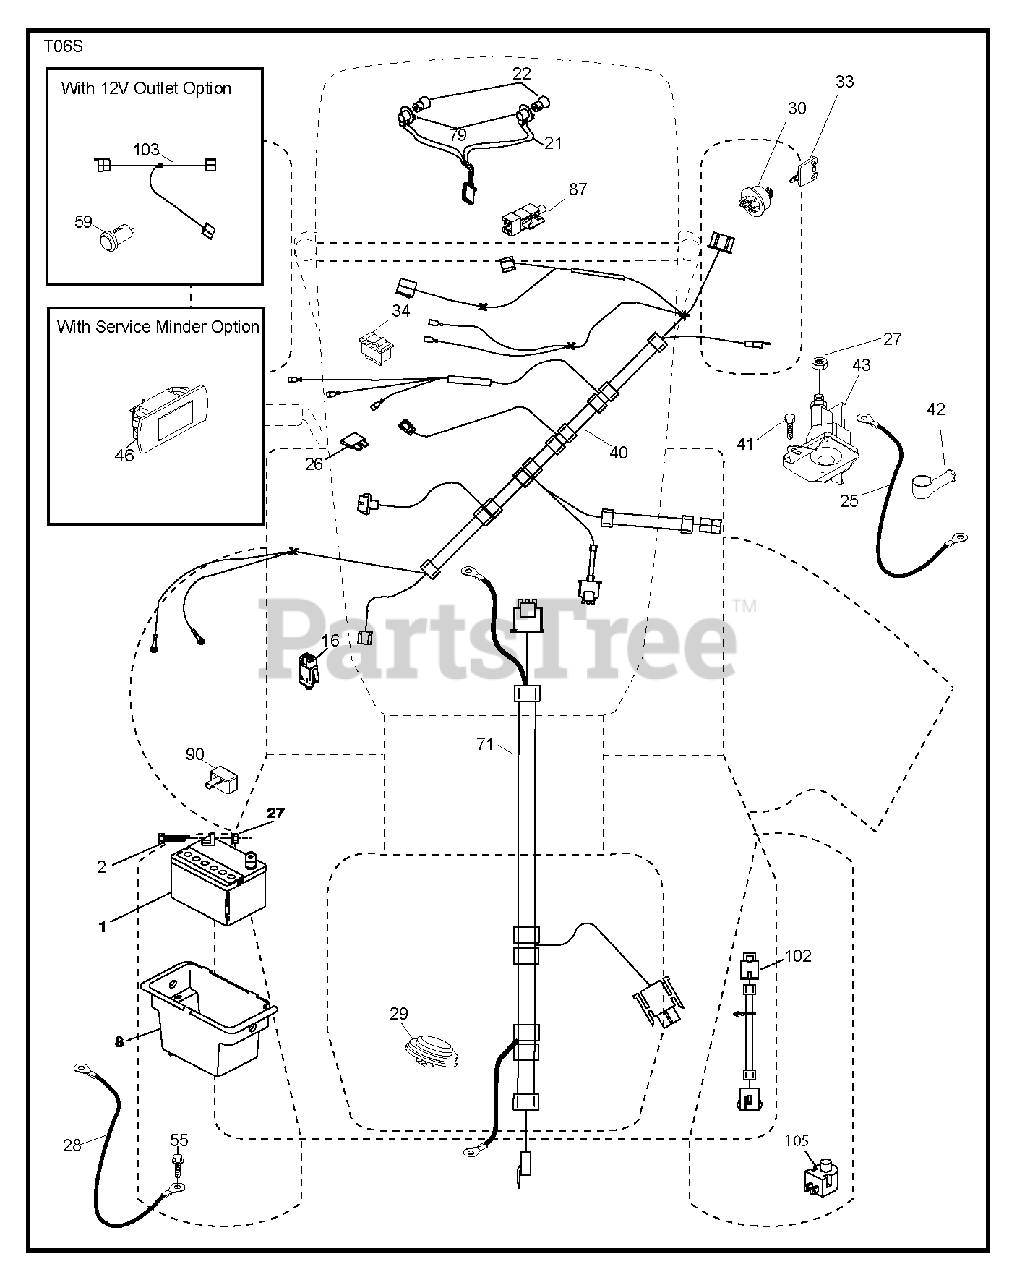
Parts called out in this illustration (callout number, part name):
1	Battery, Dry 30 Amp
2	BOLT.HEX.1/4.X.3/4.DICHROMATE
8	BOX.BATTERY.MNT.REAR.L
16	SWITCH INTERLOOK PUSH-IN
21	HARNESS.LIGHT W/4152J BULBS
25	CABLE.BATT.RED.8GA.17
26	FUSE 20AMP
27	NUT
28	CABLE.GROUND.REAR.BATTERY.8G
29	SWITCH.SEAT.DELTA.OPC.
30	SWITCH.IGN.DELTA.W.LGH.ROS
33	KEY.CHAIN.BLISTER.PACK.GEN.USA
40	HARNESS IGN. DASH
41	SCREW
42	TERMINAL COVER
43	SOLENOID.W/BRASS.PLUNGER
46	RP GUAGE.SRVCMNDR.HRMTR.
55	SCREW 5/16"
71	HARNESS.TEX.CHSSIS.REAR.BATT
79	BULB HOLDER ASM.
87	SWITCH.INTRLCK.CLUTCH.
90	COVER.TERMINAL.BATTERY
102	HARNESS PIGTAIL PCH TEX ROS
105	REVERSE SWITCH
